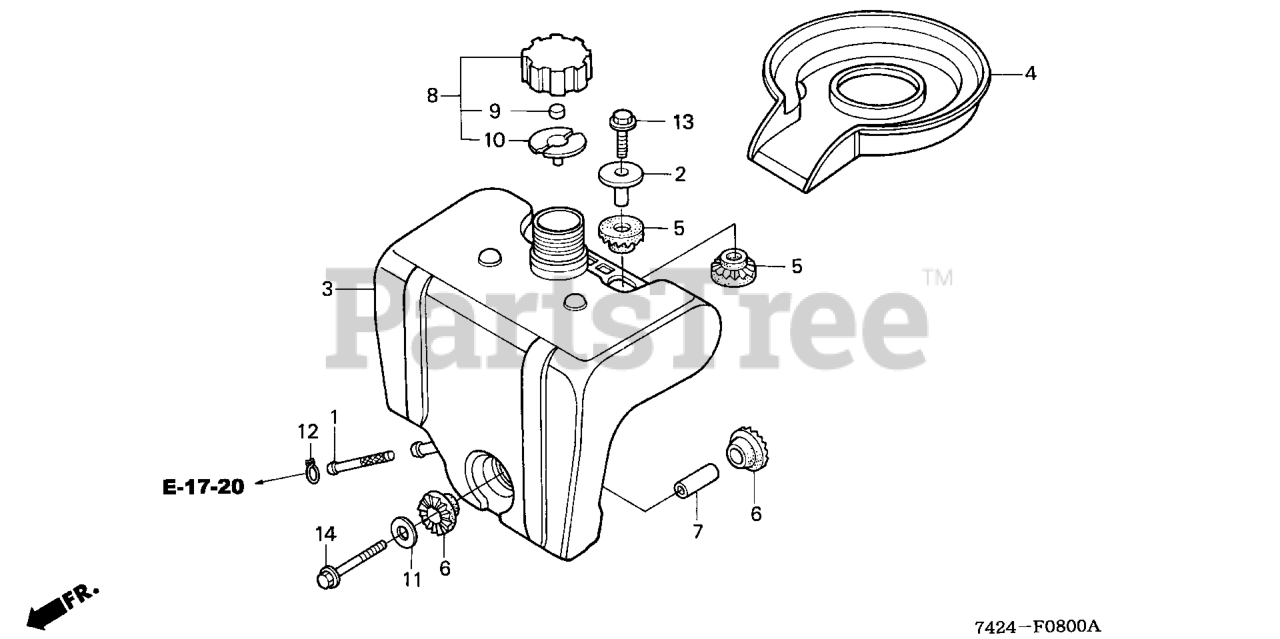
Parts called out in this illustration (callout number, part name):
1	FILTER, FUEL
2	COLLAR, FUEL TANK
3	TANK, FUEL
4	SEAL, FILLER NECK
5	RUBBER, TANK MOUNTING
6	RUBBER B, TANK MOUNTING
7	COLLAR, TANK SETTING
8	CAP ASSY., FUEL TANK
9	SPONGE, FUEL CAP BREATHER
10	GASKET, FUEL CAP
11	WASHER, TANK MOUNTING
12	CLIP, TUBE (C11)
13	BOLT, FLANGE (6X32)
14	BOLT, FLANGE (8X50)
